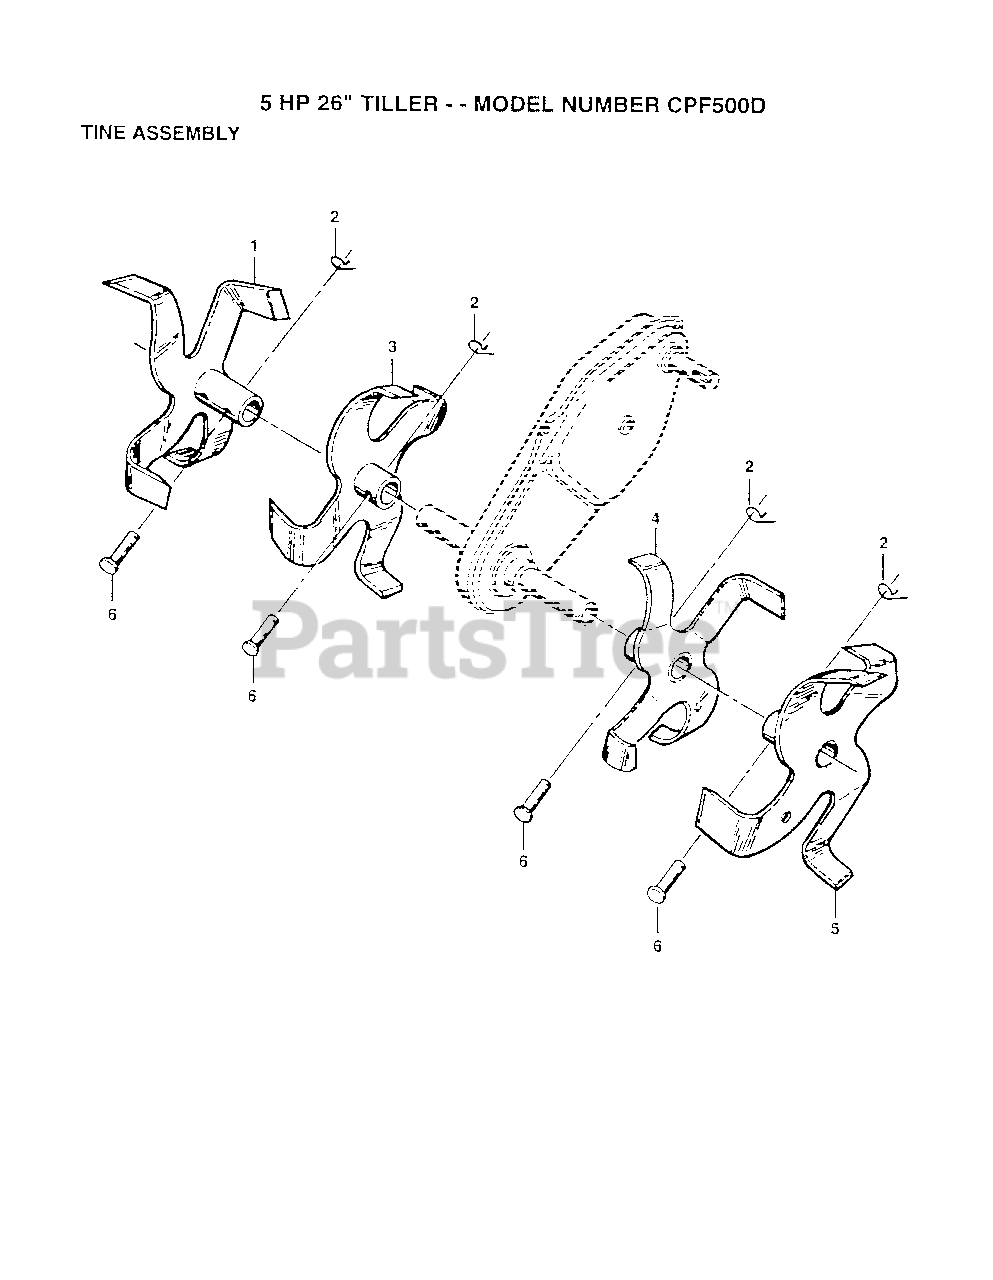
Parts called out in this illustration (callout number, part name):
1	TINE WELDMENT TI
2	RETAINER.SPRING
3	TINE TI
4	TINE TI
5	TINE WELDMENT TI
6	RIVET.PAN HD.1.75
